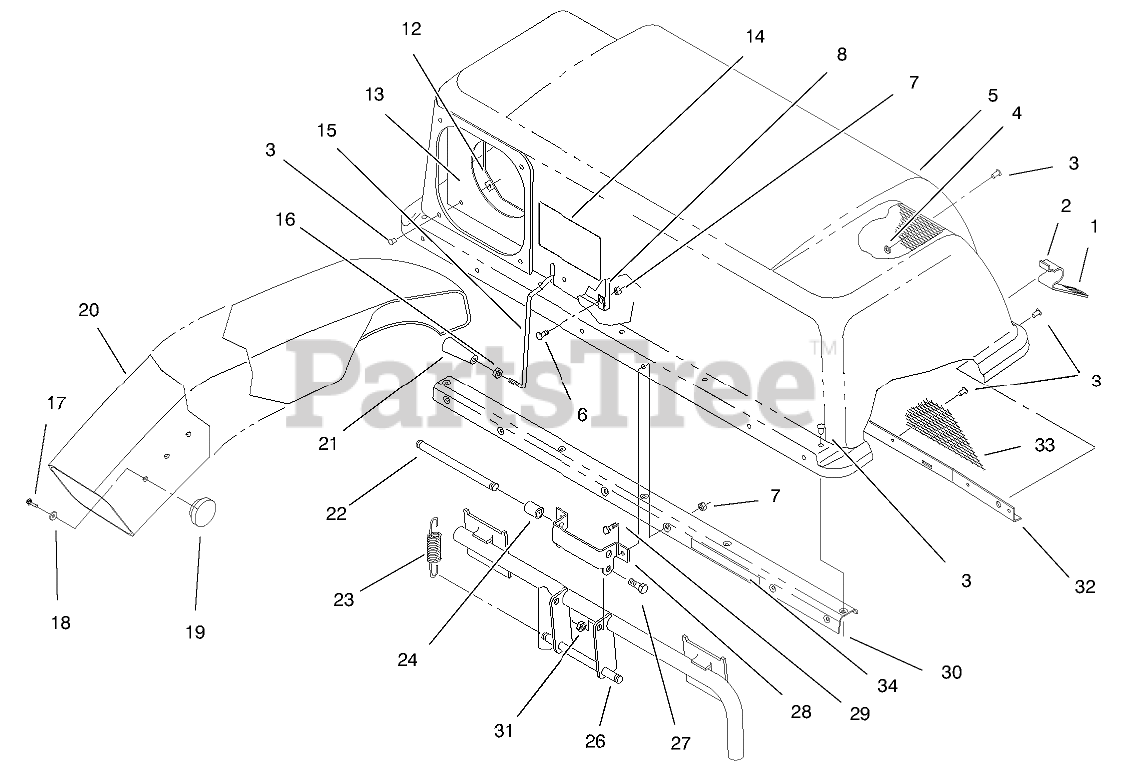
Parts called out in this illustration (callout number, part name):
2	Latch-Bag
3	RIVET-BLIND
4	WASHER-FLAT
5	TOP-BAGGER
6	SCREW-PPH
7	NUT-LOCK, NI
8	CLAMP
12	CLAMP-SEAL
13	SEAL-CHUTE
14	DECAL
15	FEELER-FILL, BAG
16	NUT-JAM
17	SCREW-PPHTF
18	WASHER-PLAIN
20	CHUTE-DISCHARGE
21	HANDLE-TAPERED
22	PIN-SPRING
23	SPRING-EXTENSION
24	Spacer
26	FRAME ASM
27	SCREW-HH
28	HINGE-BAG TOPB
29	SCREW-HH
30	Stiffener Assembly (Incl. Ref. #34)
31	NUT-LOCK, NI
32	Screen Support
33	SCREEN-BAGGER
34	DECAL-CAUTION
